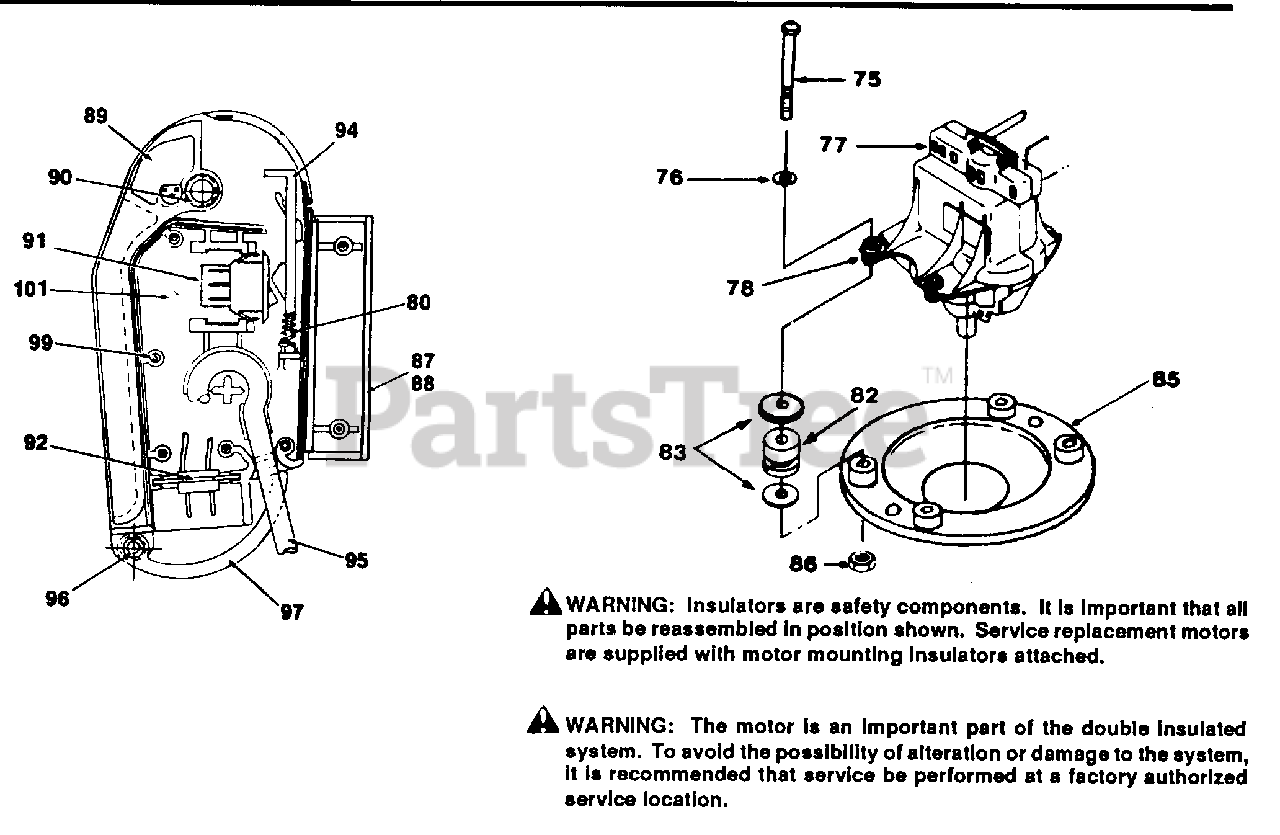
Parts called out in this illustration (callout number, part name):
75	Screw
76	Washer
77	Motor 8 Switch Ass'y Complete
78	Insulator
80	Latch Spring
82	Grommet Assembly
83	Washer
85	Motor Shield
86	Locknut 1/4" - 20
87	Housing - Upper Half
89	Handle- Switch
90	Spring
91	Switch
92	Plug Assembly
94	Latch
95	Cord Assembly
96	Spring - Plug Retainer
97	Plug Retainer
